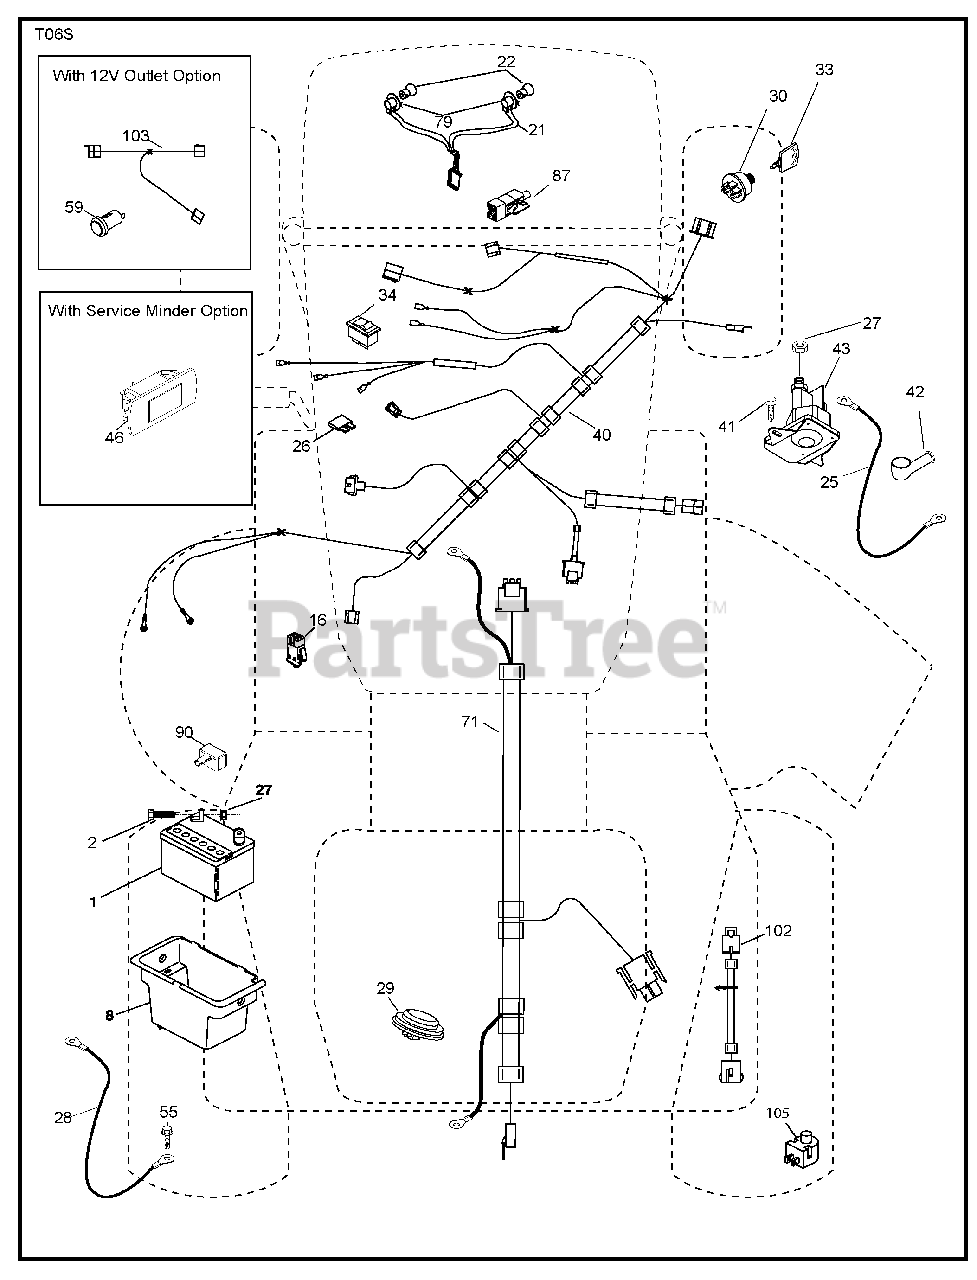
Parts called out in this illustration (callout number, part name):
1	Battery
2	Bolt Hex Head 1/4-20 x 3/4
8	Box Battery
16	Switch Interlock Push-In
21	Harness Socket Light w/4152J
22	Bulb Light
25	Cable Starter
27	Nut Keps Hex 1/4-20 unc
28	Cable, Ground
29	Switch, Seat
30	Switch, Ign
33	Key / Chain
34	Switch Light / Reset
40	Harness Ign.
41	Screw Thd Cut 1/4-20 x 1/2
42	Cover, Terminal
43	Solenoid
46	Gauge Hourmeter
55	Screw Thdrol 5/16-18 x 3/4 TYTT
71	Harness Ign. Dash
79	Socket Asm. Bulb Twistlock
87	Switch Interlock Clutch Cable
90	Cover Terminal
102	Harness Pigtail
105	Switch Reverse TT GT
